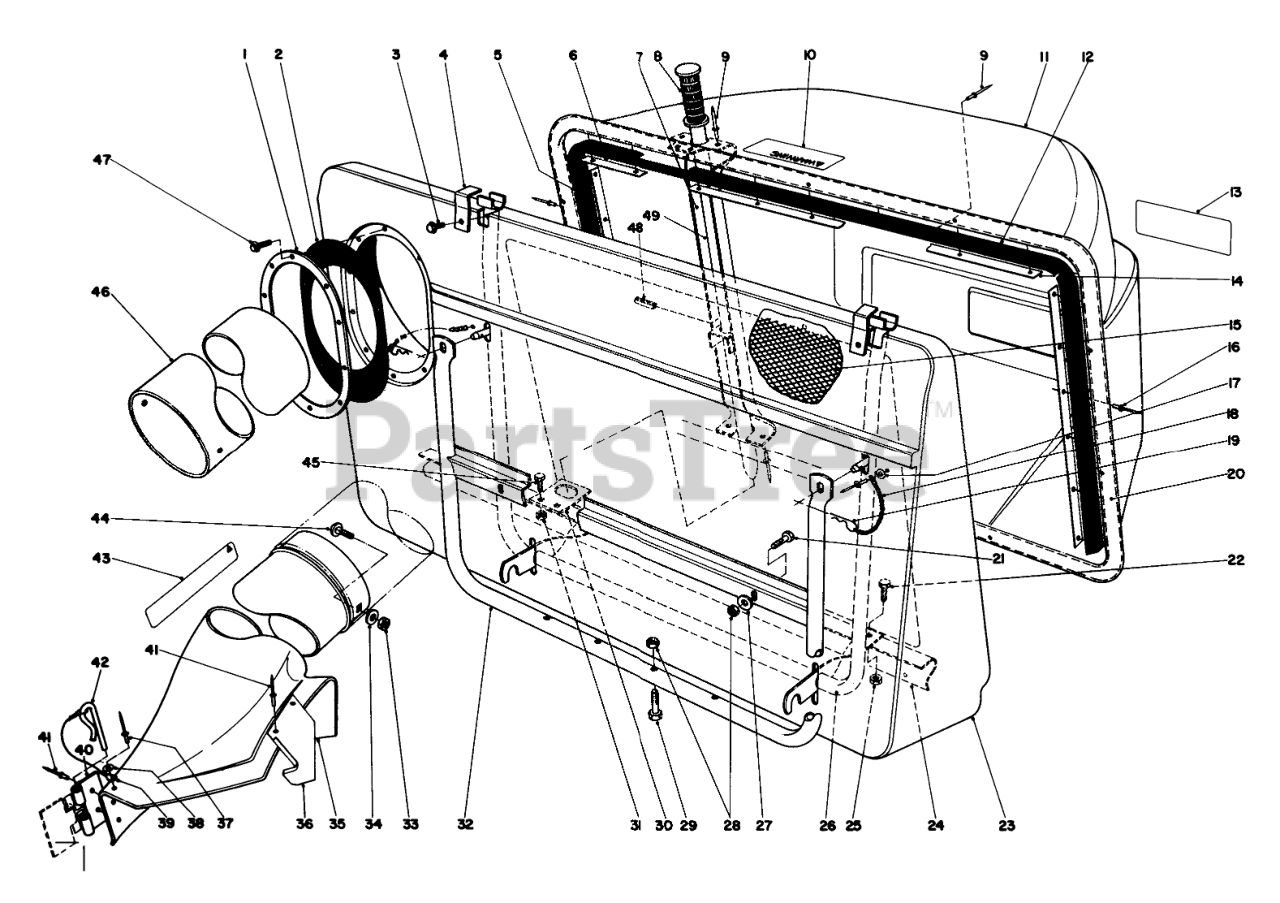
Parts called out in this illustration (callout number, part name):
1	RING-RETAINING
2	RING-RETAINER, RUBBER
3	SCREW-HWH
4	RETNR PIVOT BRKT
5	RH BAG SEAL
6	RETNR TOP EXT.
7	DUMP HDLE CHANL WA
10	Decal-Bag
11	REAR GRASS BASKET
12	Seal-Bag LH.
13	EASY EMPTY BAG DECAL
14	BAG RETNR EXT.
15	Screen Bag
17	WASHER
18	10 LINK CHAIN W/O HOOK
19	PIN-HAIR
20	BAG SUPT ASM FRM
21	SCREW-HH
22	SCREW-HH
23	Bag Front
24	FRAME SUPT BRKT B
25	NUT-LOCK, CONE
26	Bag Frame
27	WASHER-PLAIN
28	NUT-LOCK, CONE
29	SCREW-HH
30	Hanger-Frame Lower
32	BAG SUPPORT WA
33	NUT-KEPS
34	WASHER-FLAT
35	Chute Assembly (Incl. Ref. #36-43)
36	CHUTE SUPT BRKT
37	RIVET-BLIND
38	Washer
39	LANYARD
40	BRACKET-MOUNTING, CHUTE
41	RIVET-BLIND
42	PIN-LOCKING, CHUTE
43	Decal-Chute
44	Bolt-Carriage
45	SCREW-HH
46	Duct
47	SCREW-HWHTF
48	PIN-ROLL
49	DUMP HANDLE ASM
